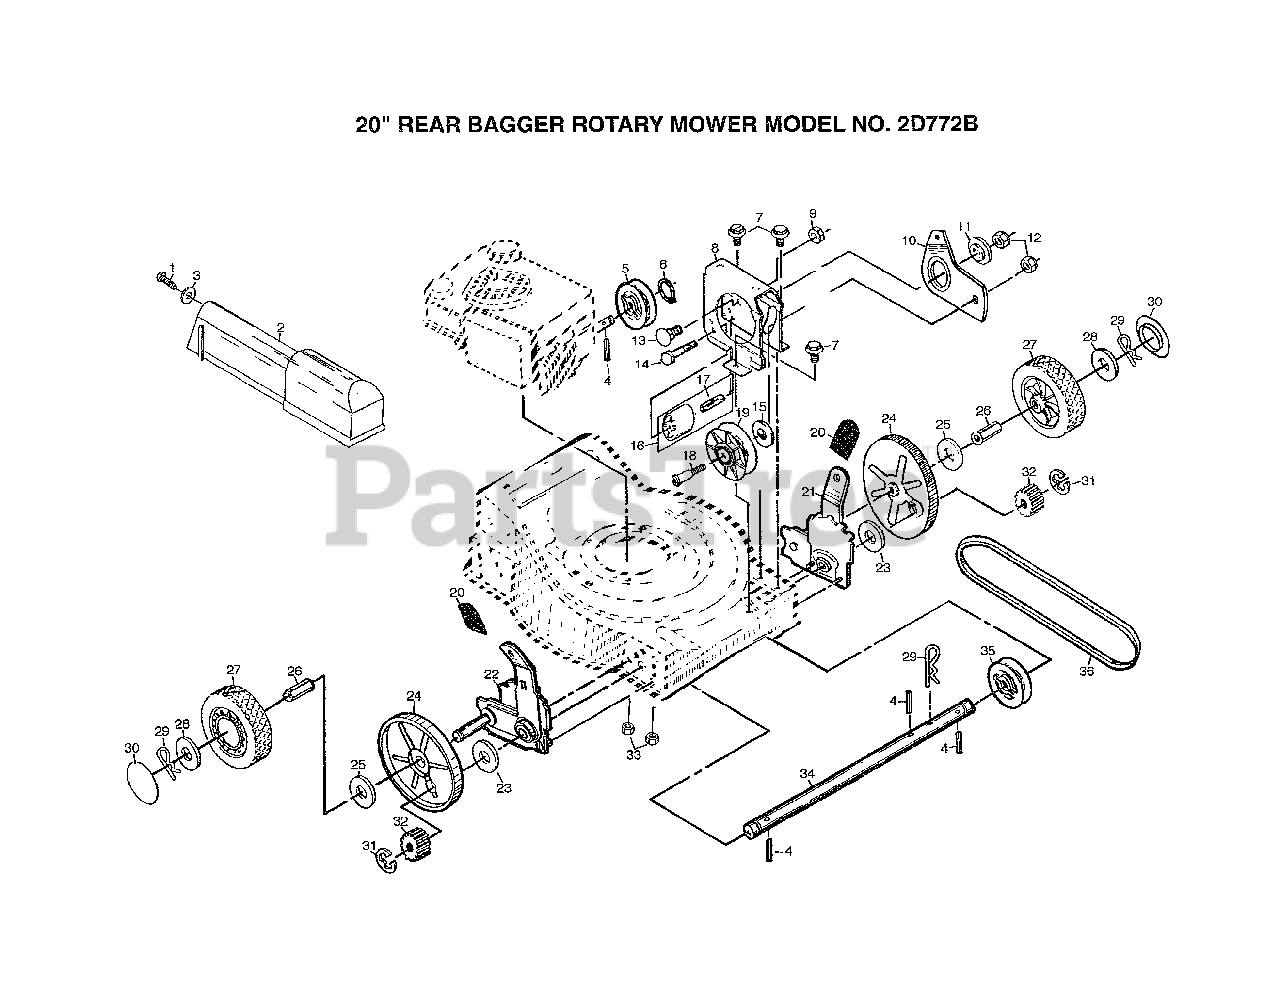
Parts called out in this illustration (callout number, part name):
1	TAPPING SCREW
4	DRIVE PAWL
6	RETAINING RING ST
7	SCREW
8	"CLUTCH,FRAME"
9	LOCKNUT
11	SPACER PM
12	LOCKNUT
13	CARRIAGE BOLT
14	BOLT 1/4-20-1 1/2
15	SPACER PM
17	IDLER SPACER
18	SHOULDER BOLT
19	IDLER PULLEY
20	KNOB PM
23	WASHER PM
24	DUST SHROUD PM
25	WASHER FLUT
26	BUSHING.HEX
27	WHEEL &TIRE ASSY
28	WASHER
29	RETAINER CLIP PM
30	HUB CAP
31	E-RING.7/16.RE.
32	PINION.GEAR
34	SHAFT.DRIVE.17.81
35	DRIVE PULLEY PM
36	"DRIVE, BELT"
